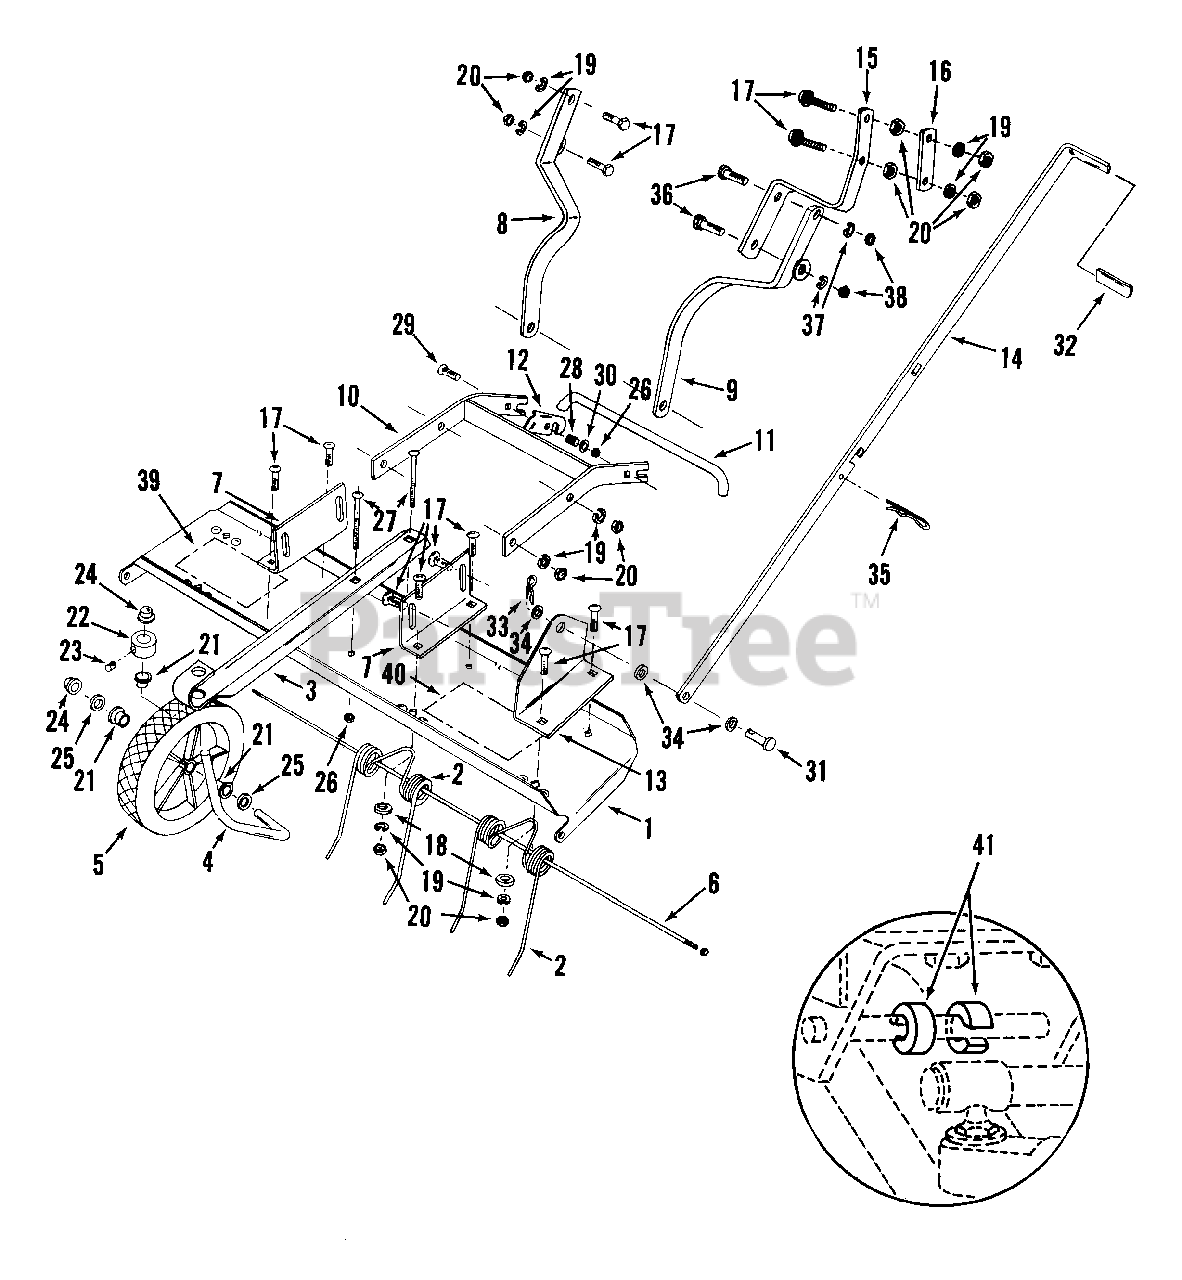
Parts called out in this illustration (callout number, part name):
1	TRAY, Tine
2	TINE, Thatching
3	SUPPORT, Wheel
4	AXLE
5	WHEEL, Gauge
6	ROD, Tine
7	BRACKET, Frame Mounting
8	BAR, Tractor Mounting, RH
9	BAR, Tractor Mounting, LH
10	ASSEMBLY, Main Frame Weldment
11	ROD, Mounting
12	LATCH, Frame Mount
13	BRACKET, Lift
14	HANDLE, Lift
15	BRACKET, Lift Handle Support
16	STRAP, Handle Retaining
17	BOLT, 5/16-18 x 1" Square Neck Carriage, Grade 5
18	WASHER, Reinforcing
19	WASHER, 5/16 Split Lock
20	NUT, 5/16-18 Hex
21	BEARING, Nyliner
22	BUSHING, Wheel Adjustment
23	SCREW, 5/16-18 x 1/4" Set
24	NUT, 1/2" Push
25	WASHER, 1/2 SAE
26	NUT, 1/4-20 Hex Top Lock
27	BOLT, 1/4-20 x 1-3/4" Square Neck Carriage
28	SPRING, Compression
29	BOLT, 1/4-20 x1-1/4" Square Neck Carriage, Grade 2
30	WASHER, 1/4 SAE
31	PIN, 5/16 Clevis
32	GRIP, Handle
33	COTTER, Hairpin
34	WASHER, 5/16 SAE
35	COTTER, Hairpin
36	BOLT, 3/8-16 x 1-1/4" Hex Head Cap, Grade 5
37	WASHER, 3/8 Split Lock
38	NUT, 3/8-16 Hex, Grade 5
39	DECAL, Logo
40	DECAL, Adjustment
41	RING, Spacer
